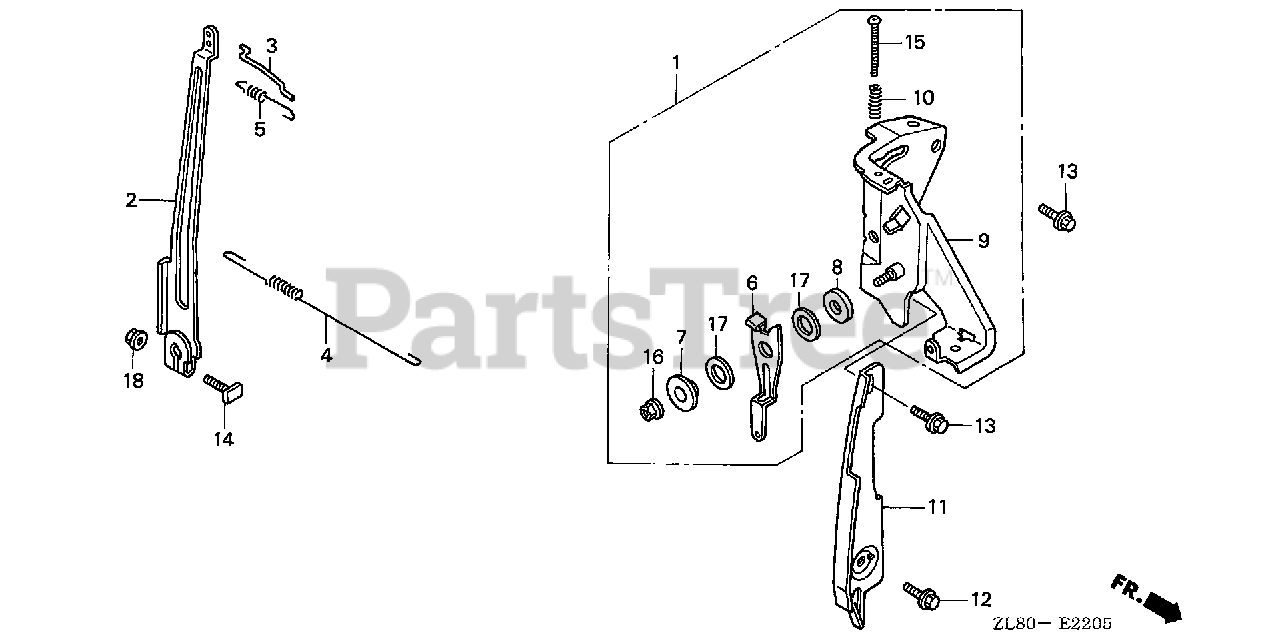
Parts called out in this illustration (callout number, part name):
1	CONTROL ASSY.
2	ARM, GOVERNOR
3	ROD, GOVERNOR
4	SPRING, GOVERNOR
5	SPRING, THROTTLE RETURN
6	LEVER, CONTROL
7	WASHER, CONTROL LEVER
8	SPACER, CONTROL LEVER
9	BASE, CONTROL
10	SPRING, CONTROL ADJUSTING
11	PLATE, SIDE
12	BOLT, FLANGE (6X12) (CT200)
13	BOLT, FLANGE (6X14) (CT200)
14	BOLT, GOVERNOR ARM
15	SCREW, ADJUST
16	NUT, SELF-LOCK (6MM)
17	WASHER (12.5MM)
18	NUT, FLANGE (6MM)
